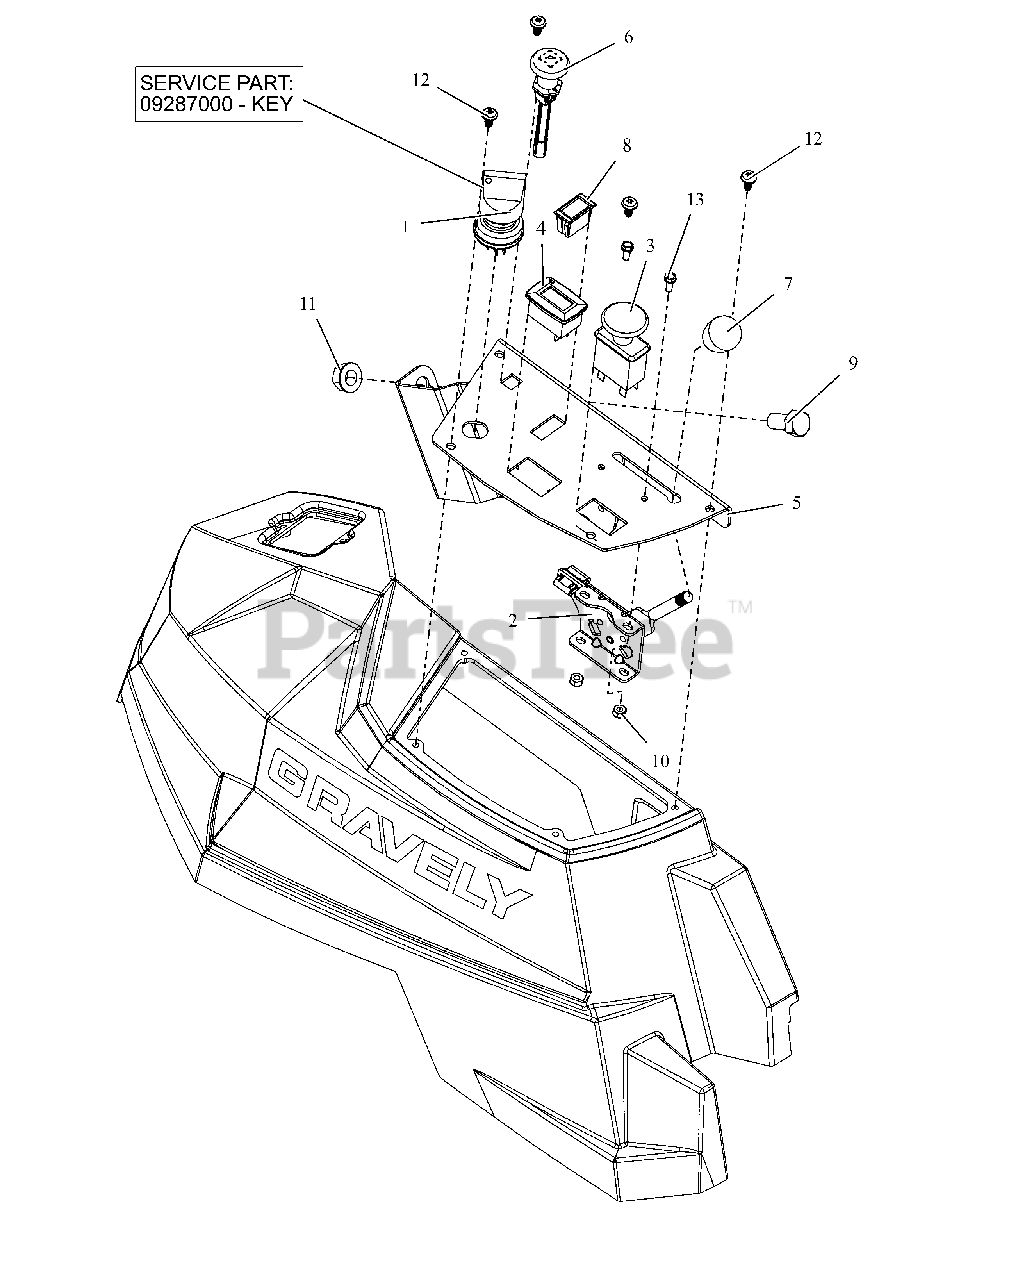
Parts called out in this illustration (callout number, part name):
1	SWITCH, IGNITION
1	KEY, W/ SHIELD
2	CABLE, PRO THROTTLE CONTROL
3	SWITCH, CLUTCH
4	METER, HOUR W/MAINTENANCE
5	PANEL, HD CONTROL
6	CABLE - CHOKE, SNAP-IN
7	KNOB-CONTROL-BLACK .38-16X.50
8	SWITCH,BLANK
9	BLT, HEX .50-13X1.00 G5 ZCC
10	NUT-LK-NYL #10-24 G2 ZCC
11	NUT-LK-TOP-FLG .500-13 GF ZCC
12	SCR-PAN .25-15X.50 6L H/LZB500
13	BLT, HWH #10-24X.50 ZCC
